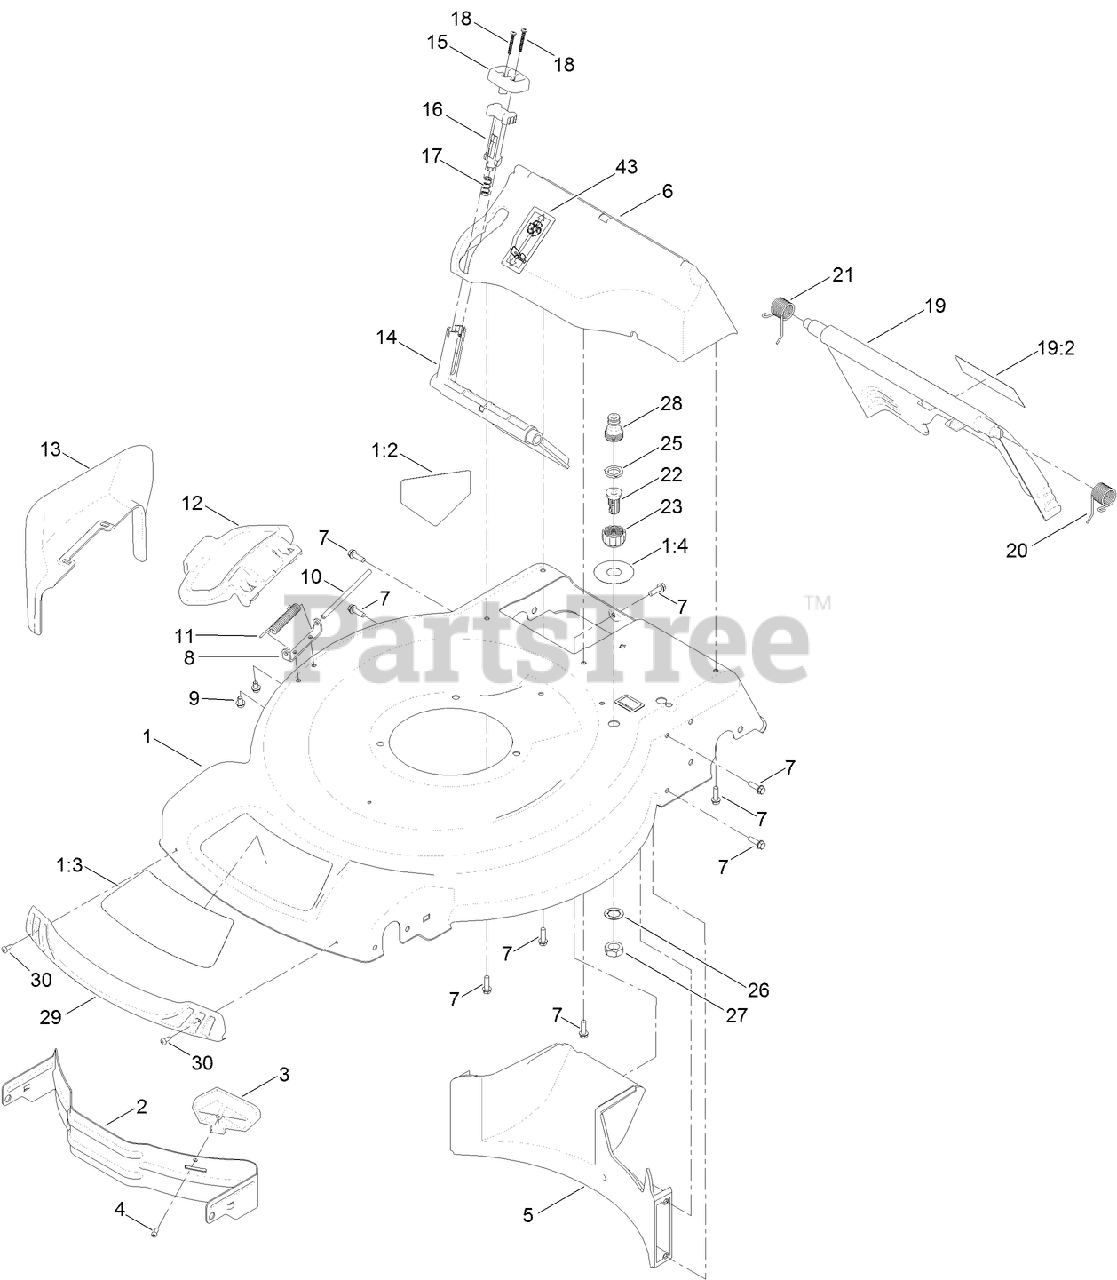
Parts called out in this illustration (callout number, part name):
1	HOUSING ASM
1:2	DECAL-DANGER
1:4	DECAL-PORT, WASHOUT
2	BAFFLE-FRONT
3	KICKER-FRONT
4	SCREW-PPH
5	BAFFLE-REAR
6	CHUTE-RECYCLE
7	SCREW-HWH
8	BRACKET-COVER
9	SCREW-HWH
11	SPRING-TORSION
12	DEFLECTOR-SIDE
13	CHUTE-DISCHARGE, SIDE
14	DEFLECTOR-RECYCLE
15	KNOB-RECYCLE
16	LATCH-RECYCLE
17	SPRING-COMPRESSION
18	SCREW-PPH
19:2	DECAL-WARNING
20	SPRING-TORSION
21	SPRING-TORSION
22	PORT-WASHOUT
23	COUPLING-HOSE, WASHOUT PORT
25	WASHER-SEAL, WASHOUT PORT
26	WASHER-LOCK
27	NUT-JAM
28	ADAPTER-CONNECT, QUICK
29	BUMPER
30	SCREW-FORMING, THREAD
